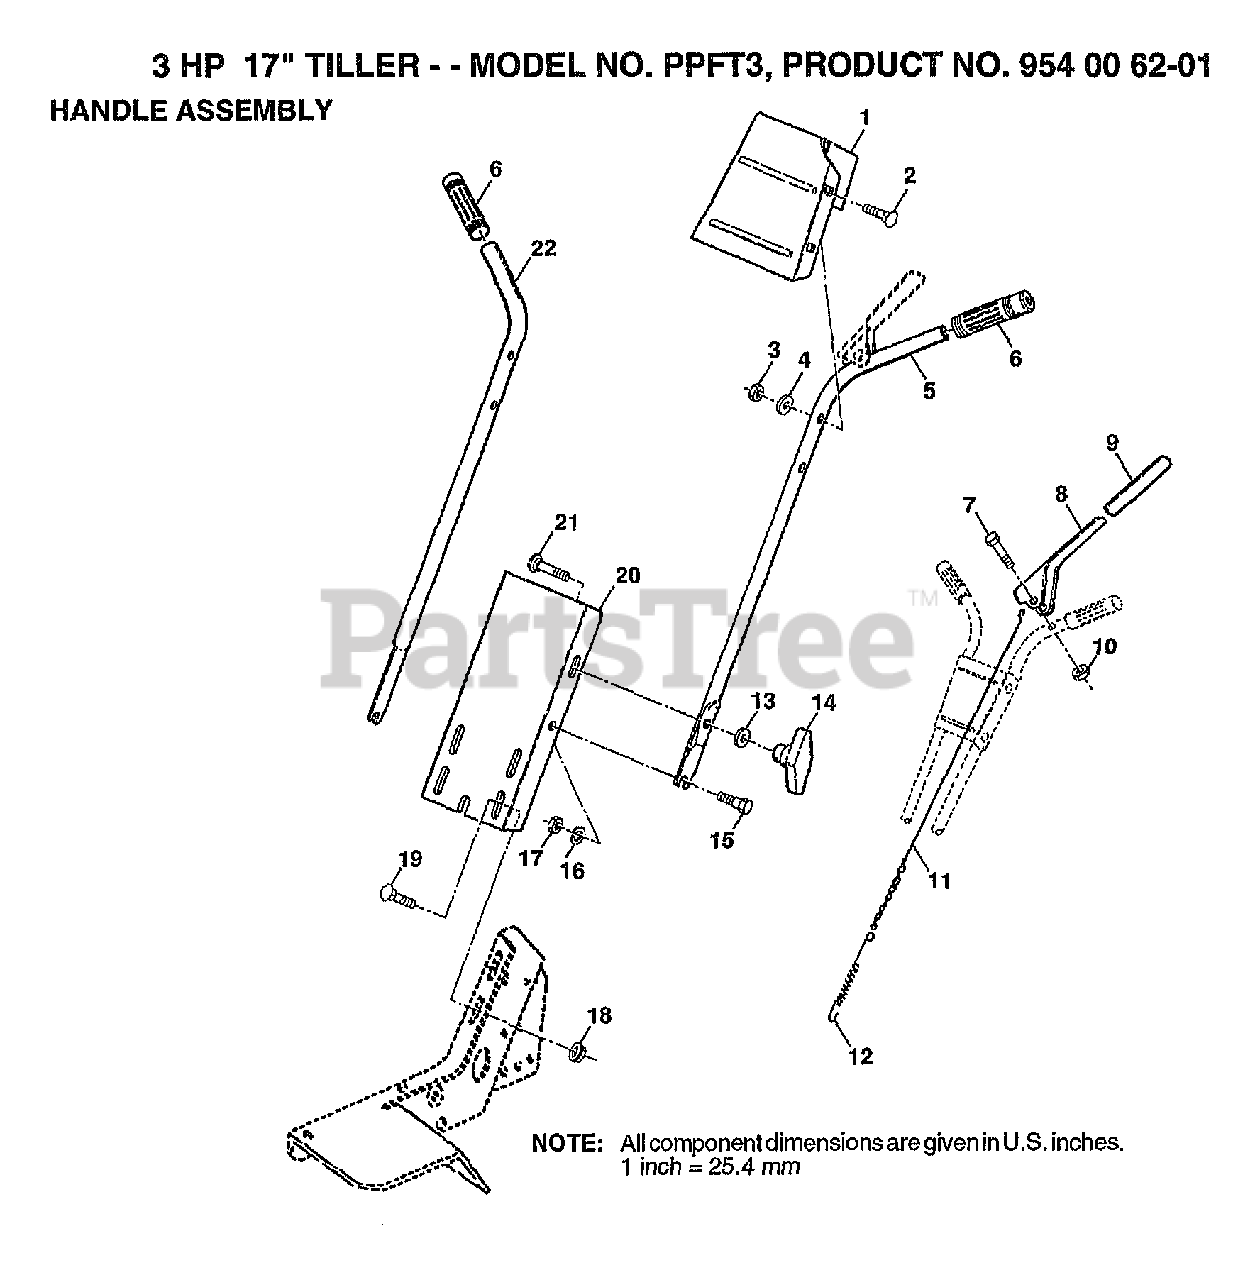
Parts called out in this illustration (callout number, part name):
2	BOLT, CARRIAGE
3	LOCKNUT, CROWN 5/16-18
4	WASHER 11/32 X 11/16 X 16 GA.
7	BOLT, HEX 5/16-18 X 1-1/2
13	WASHER 3/8 X 7/8 X 14 GA.
18	NUT, FLANGED
19	BOLT, CARRIAGE
